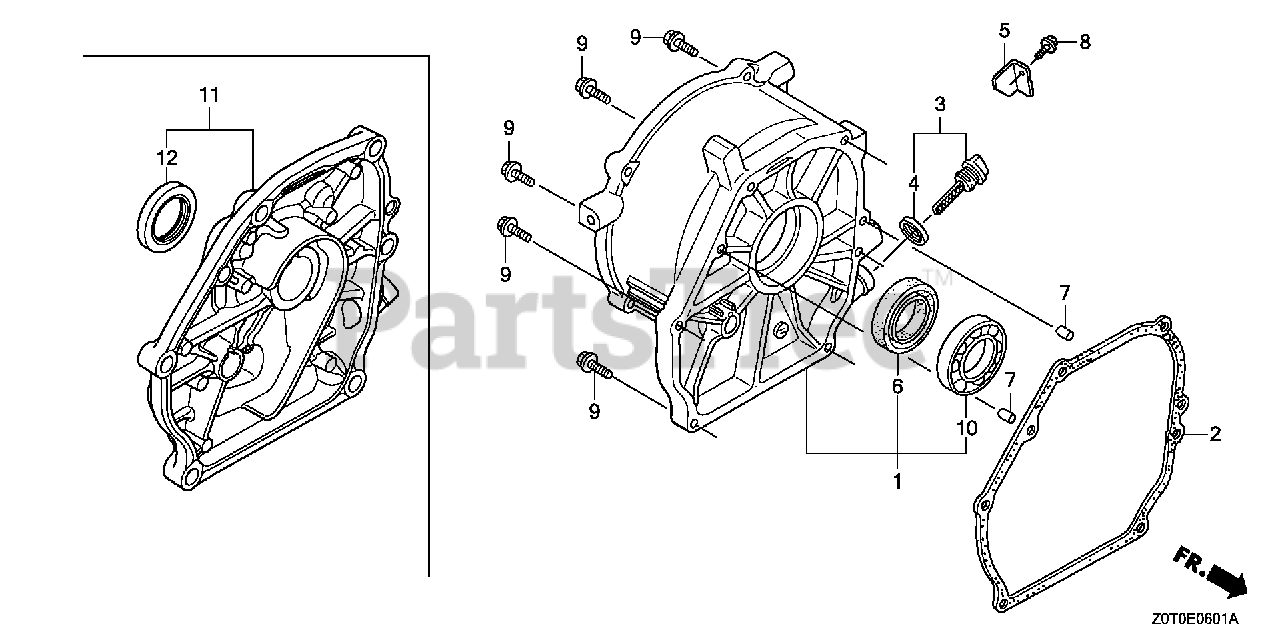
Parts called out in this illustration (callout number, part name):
2	GASKET, CASE COVER (NON-ASBESTOS)
3	CAP ASSY., OIL FILLER
4	GASKET, OIL FILLER CAP
7	PIN A, DOWEL (8X14)
9	BOLT, FLANGE (8X32)
11	COVER ASSY., CRANKCASE
12	OIL SEAL (25X41X6)
